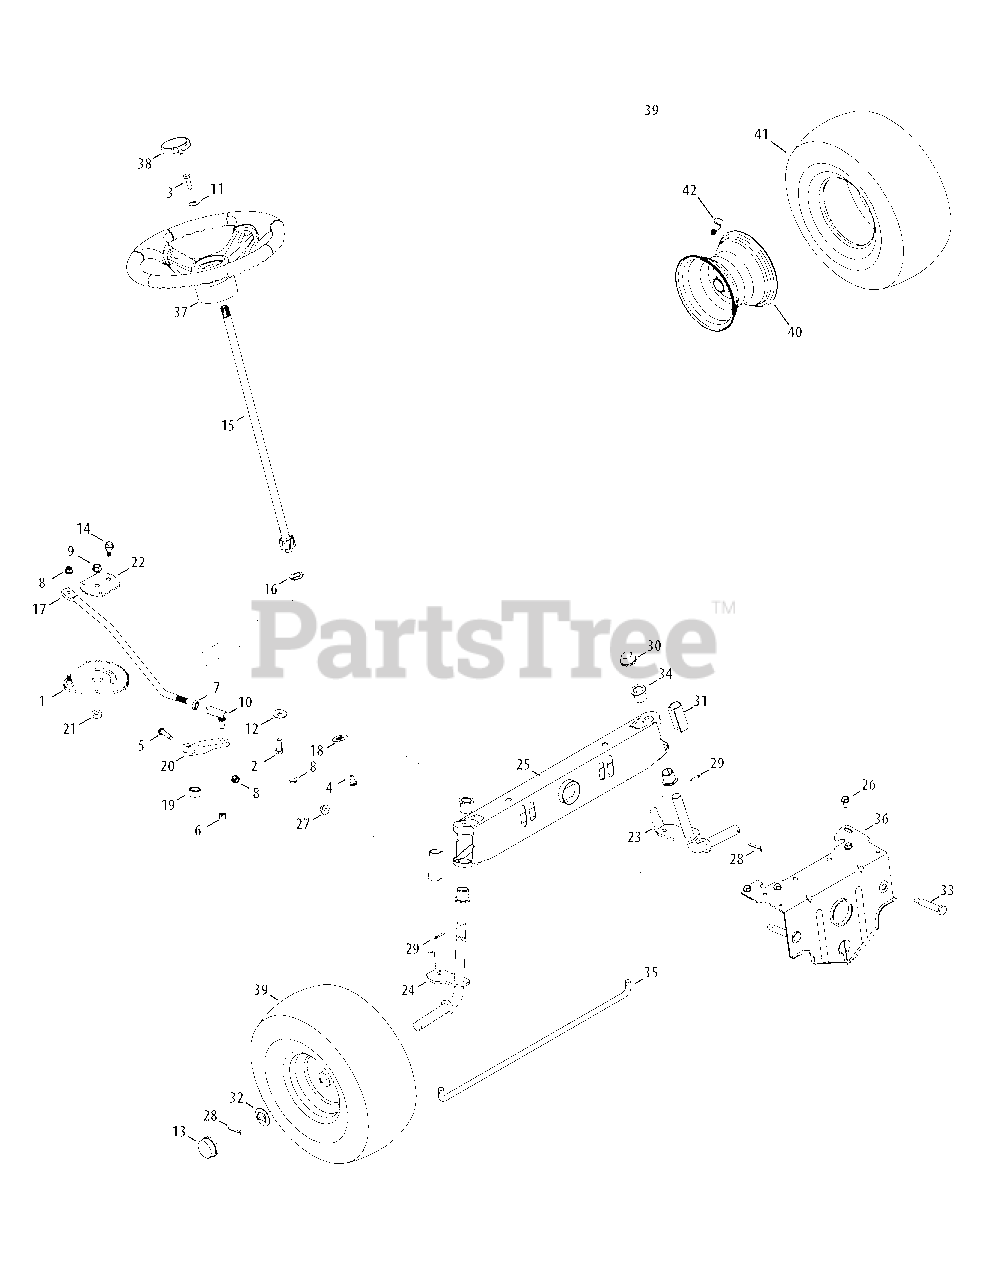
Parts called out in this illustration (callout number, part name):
1	Gear Assembly, Steering
2	Hex Head Screw, 3/8-16 x 1.00
3	Screw, 5/16-18, 1.00, Gr5, Lock
4	Screw, Mach, 5/16-18, 0.750
5	Screw, 5/16-18, 1.75, Gr5
6	Nut, Jam Lock, 3/8-24
7	Nut, Jam, 7/16-20, Gr2
8	Nut, Flange Lock, 5/16-18, Grf
9	Nut, Flange Lock, 3/8-16, Grf
10	Ball Joint, 7/16-20, Lock
11	Washer, Bell, .340 x .872 x .060
12	Bevel Washer, .390 x 1.130 x .062
13	Hub Cap
14	Shoulder Screw, 5/16-18
15	Steering Shaft, 5/8 Spline
16	Bearing, Flange, Hex 5/8
17	Drag Link, Steering
18	Cap, 1.25 x .16
19	Spacer, .710 ID x .125 OD x .56
20	Steering, Block
21	Spacer, .38 x .854 x .20
22	Stabilizer Gear Plate
23	Axle Assembly LH
24	Axle Assembly RH
25	Pivot Bar Axle Assembly
26	Screw, 5/16-18, 0.750
27	Nut, Flange Lock, 3/8-16, GrF
28	Pin, Cotter, 5/32, 1.25
29	Pin, Cotter, 1/8 x 0.75
30	Push Cap, 3/4
31	Axle Cap
32	Washer, Flat, .781 x 1.59
33	Screw, Shlder, .500 x 2.380, 3/8-16
34	Flange Bearing
35	Tie Rod
36	Pivot Bar Bracket
37	Steering Wheel, Softgrip
38	Cap, Steering Wheel (Crafts. logo)
39	Wheel Assembly
41	Tire, 15 x 6 x 6 Rd. Shoulder
42	Valve Stem
